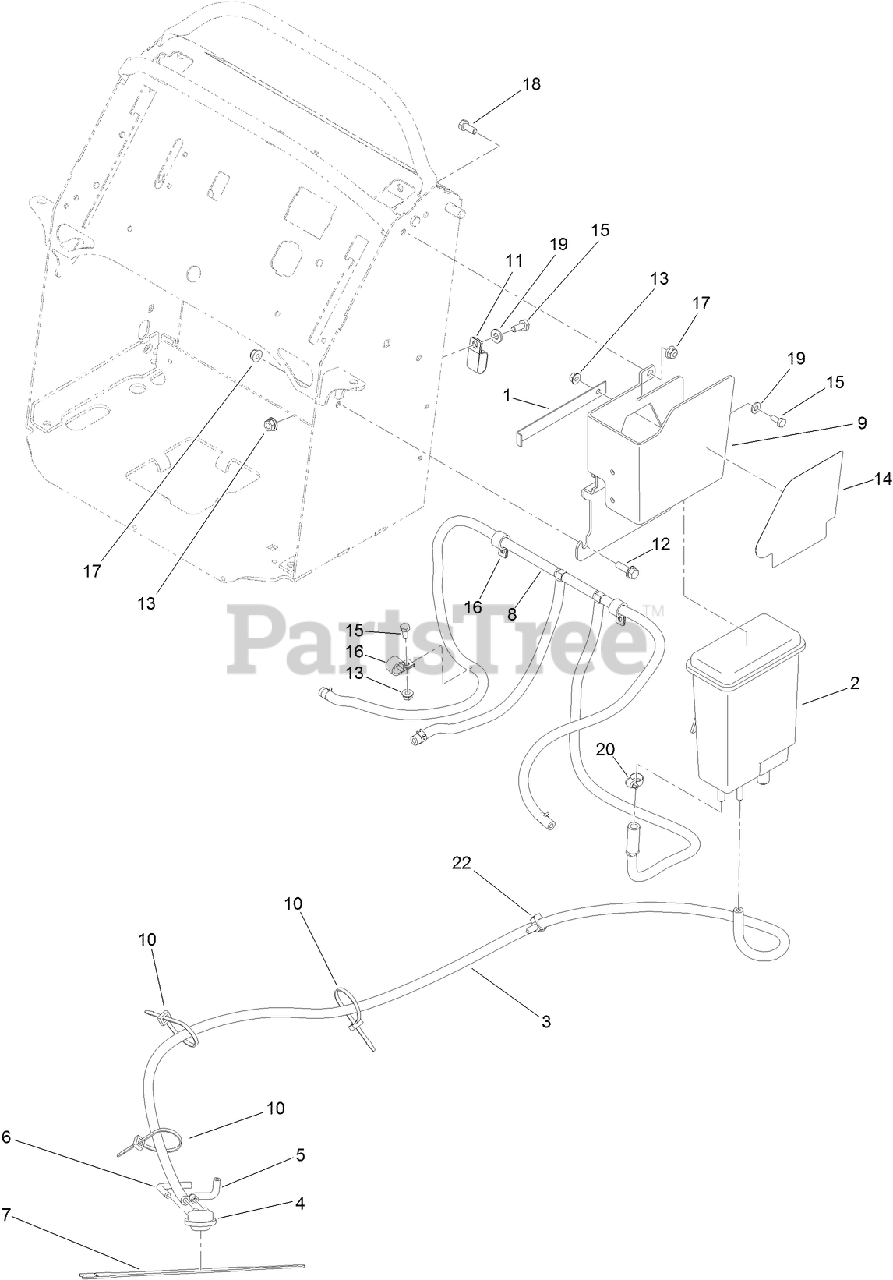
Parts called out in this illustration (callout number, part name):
1	PLATE-LOC
2	CANISTER-CARBON, 1200CC
3	HOSE-FUEL
4	VALVE-CONTROL, VACUUM
5	HOSE-VENT, FORMED
6	HOSE-VENT, FORMED
7	STRAP-VELCRO, CABLE TIE
8	VENT HOSE ASM
9	PLATE- ADAPTER
10	TIE-CABLE
11	CLAMP-TUBE, DOUBLE
12	SCREW-HHF
13	NUT-HHF
14	DECAL-SERVICE/SPARK ARREST
15	SCREW-HH
16	CLAMP-CABLE
17	NUT-HF, NI
18	SCREW-HH
19	WASHER-FLAT
20	CLAMP-WORM
22	CLIP-HARNESS
